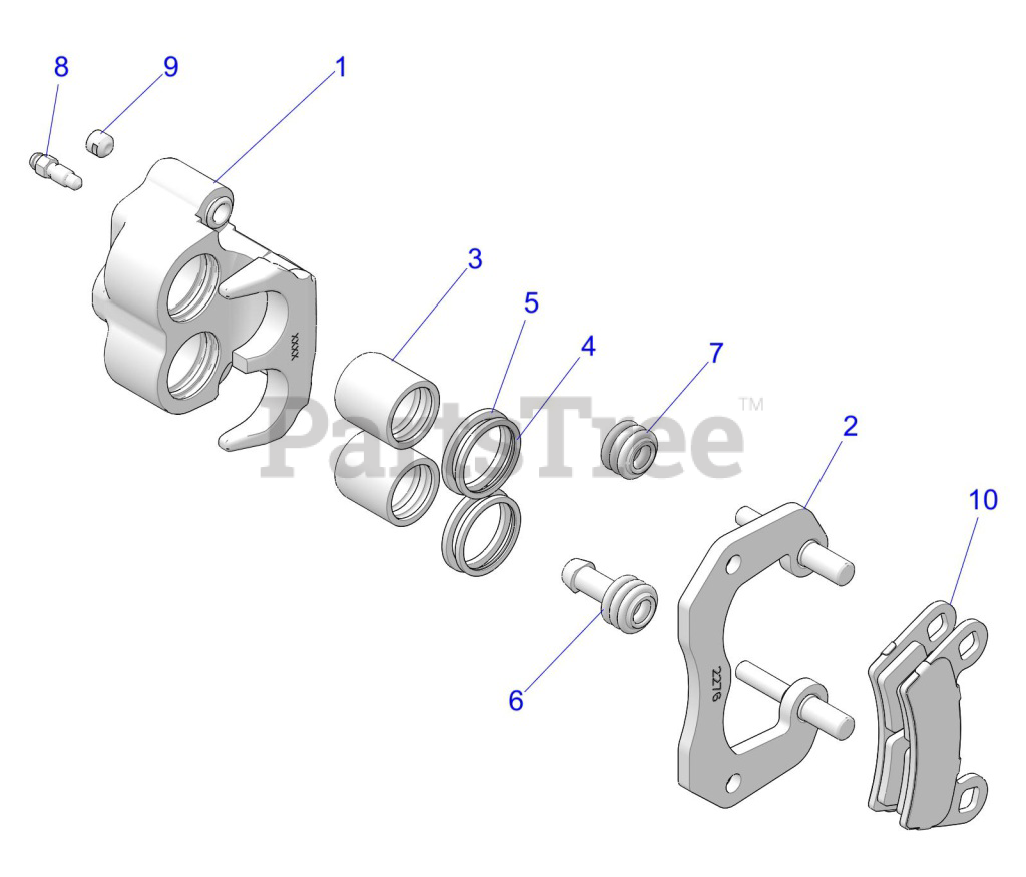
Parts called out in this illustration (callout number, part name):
1	ASM-CLPR-DB1.18-LH-GROOVED
1	ASM-CLPR-DB1.18-RH-GROOVED
2	ASM-CALIPER MNT-DB-3.0"-APX
3	PISTON-BRAKE-1.188"-AL-GROOVED
4	RING-SQUARE-MOLDED-.094
5	RING-SQUARE-MOLDED-.103X.134
6	BOOT-PIN BUSHING
7	BOOT-PIN SEAL
8	SCR-M7X1.0-BLEEDER-OLIVE D
9	SCR-M10X1.0X8-SOC SET-OD
10	ASM-BRAKE PAD- DUAL BORE
